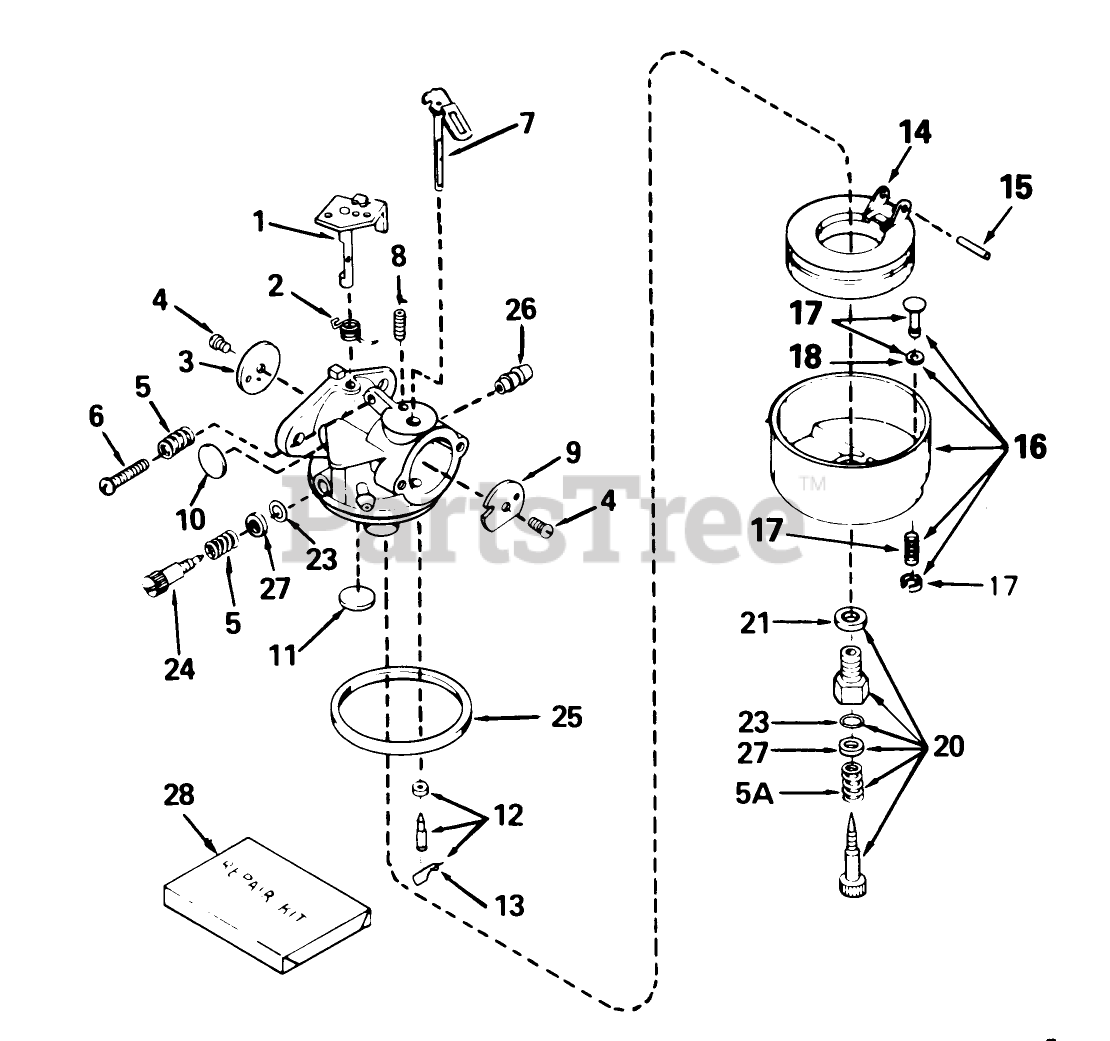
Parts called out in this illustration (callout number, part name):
1	Throttle Shaft and Lever ASM
2	Spring-Return, Throttle
3	Shutter-Throttle
4	Screw-Shutter
5	Spring-Tension
5A	Spring
6	Screw-Throttle Crack Screw / Idle Speed
7	Choke Shaft and Lever ASM
8	Spring-Positioning, Choke
9	Shutter-Choke
10	Plug-Welch, Idle Mixture Well
11	Plug-Welch, Atmospheric Vent
12	Inlet Needle, Seat Clip Assy. (Incl. No. 13)
13	Clip-Spring
14	Float
15	Shaft-Float
16	Float Bowl Asm. (Incl. Ref. # 32, 33)
17	Bowl Drain ASM
18	Gasket-Plunger, Drain
20	Adjustment Screw Assy.,Main (Incl. Ref. #5A,21,23 30)
21	Washer-Bowl Nut
23	ORing
24	Screw-Idle Mix
25	O Ring-Bowl, Float
26	Fitting-Fuel
27	Washer
28	Kit-Repair
